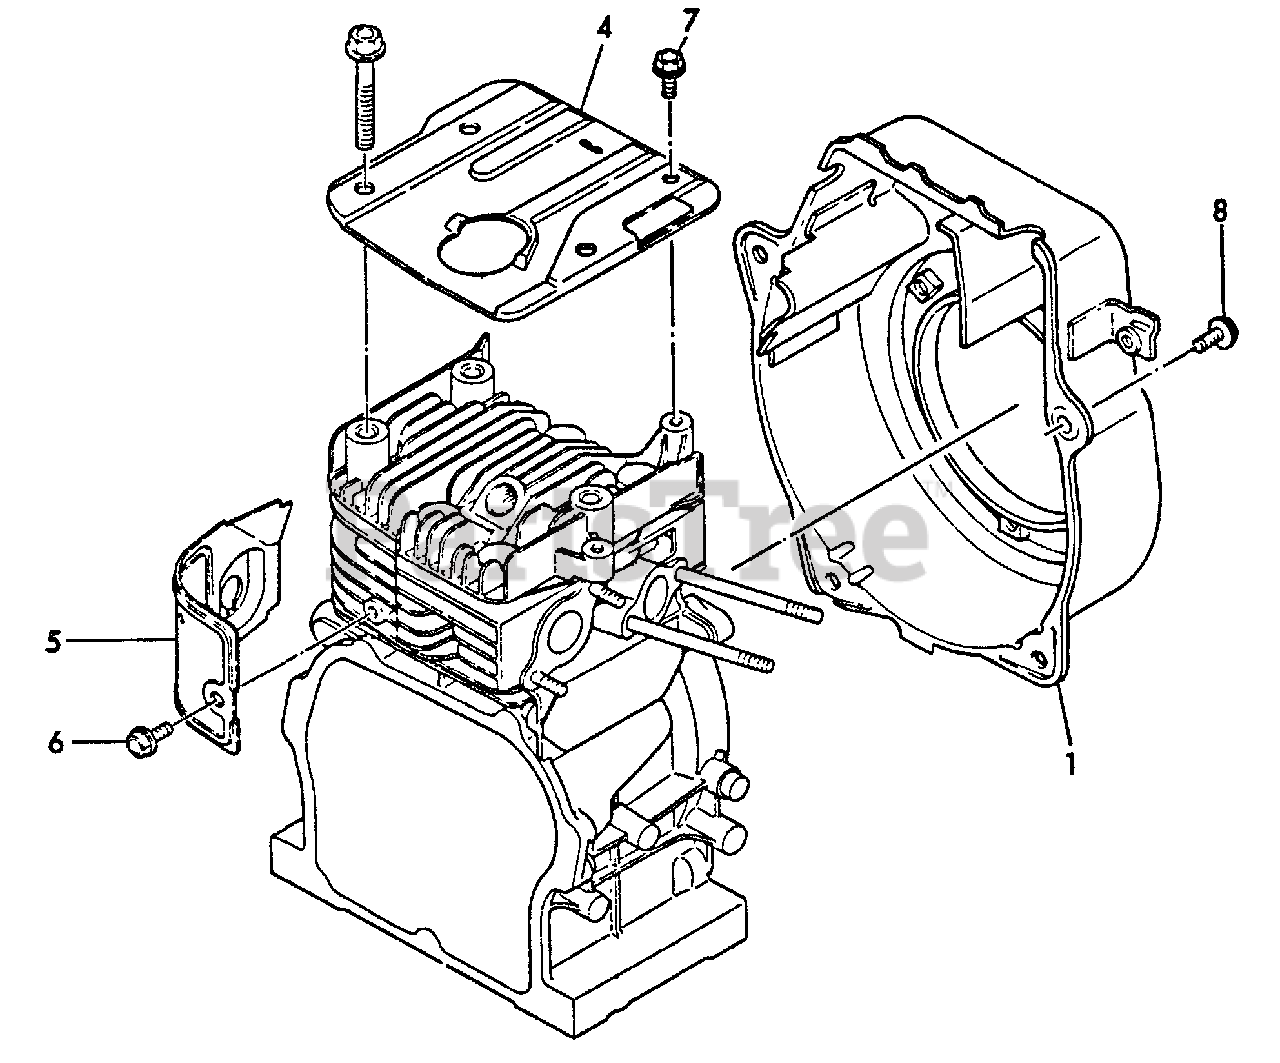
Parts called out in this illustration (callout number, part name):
1	COVER, FAN
4	COVER, CYLINDER HEAD
5	SHIELD, CYLINDER
6	BOLT - 6×8 -- PLATED
7	BOLT - 6×8 -- PLATED
8	BOLT - 6×8 -- PLATED
